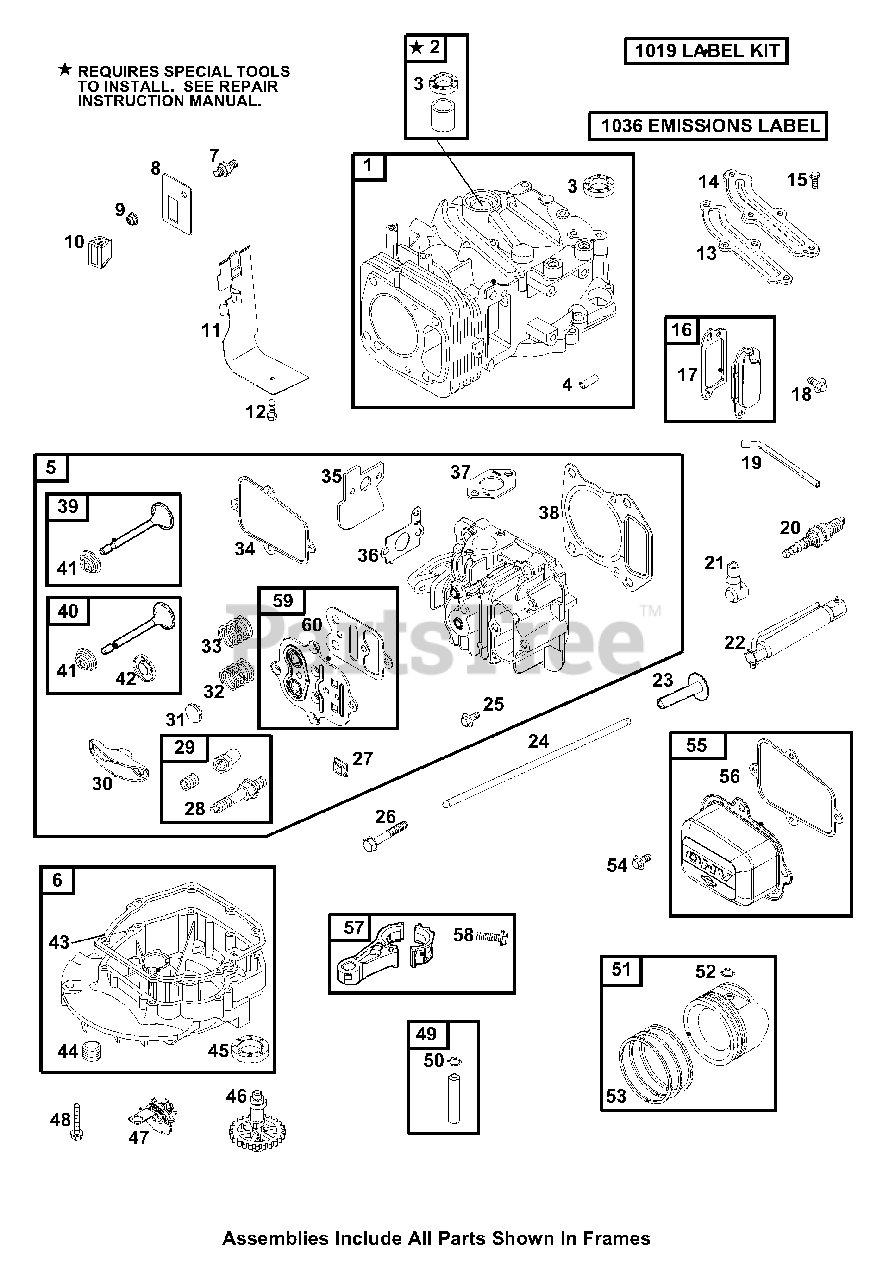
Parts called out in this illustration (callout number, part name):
1	Cylinder Assembly
2	Kit-Bushing/Seal (Magneto Side)
3	Seal-Oil (Magneto Side)
4	Pin-Locating
5	Hd.-Cyl.
6	Sump-Engine
7	Stud (mounting bracket)
8	Bracket-Mounting
9	Nut (Mounting Bracket)
10	Switch-Rocker
11	Shield-Cylinder
12	Screw (Cylinder Shield)
13	Gasket-Breather Passage
14	Cover-Breather Passage
15	Screw (Breather Passage Cover)
16	Breather Assembly
17	Gasket-Breather
18	Screw (Breather Assembly)
19	Tube-Breather
20	Plug-Spark
21	Boot-Spark Plug
22	Wrench-Spark Plug
23	Tappet-Valve
24	Rod-Push
25	Screw (Cylinder Head Plate)
26	Screw (Cylinder Head)
27	Guide-Push Rod
28	Stud (Rocker Arm)
29	Rocker Arm Ball
30	Arm-Rocker
32	Spring-Valve (Intake)
33	Spring-Valve (Exhaust)
34	Gasket (Rocker Cover)
35	Spacer-Carburetor
36	Gasket-Intake
37	Gasket-Exhaust
38	Gasket-Cylinder Head
39	Valve-Exhaust
40	Valve-Intake
41	Retainer-Valve
42	Seal-Valve
43	Gasket-Crankcase
44	Plug-Oil Drain
45	Seal-Oil (PTO Side)
46	Camshaft
47	Slinger-Governor/oil
48	Screw (Engine Sump)
49	Pin-Piston
50	Lock-Piston Pin
51	Piston Assembly
52	Lock-Piston Pin
54	Screw (Rocker Arm Cover)
55	Cover-Rocker
56	Gasket (Rocker Cover)
57	Rod-Connecting
58	Screw (Connecting Rod)
59	Plate-Cylinder Head
60	Gasket-Cylinder Head Plate
1019	Label Kit
1036	Emissions Label
